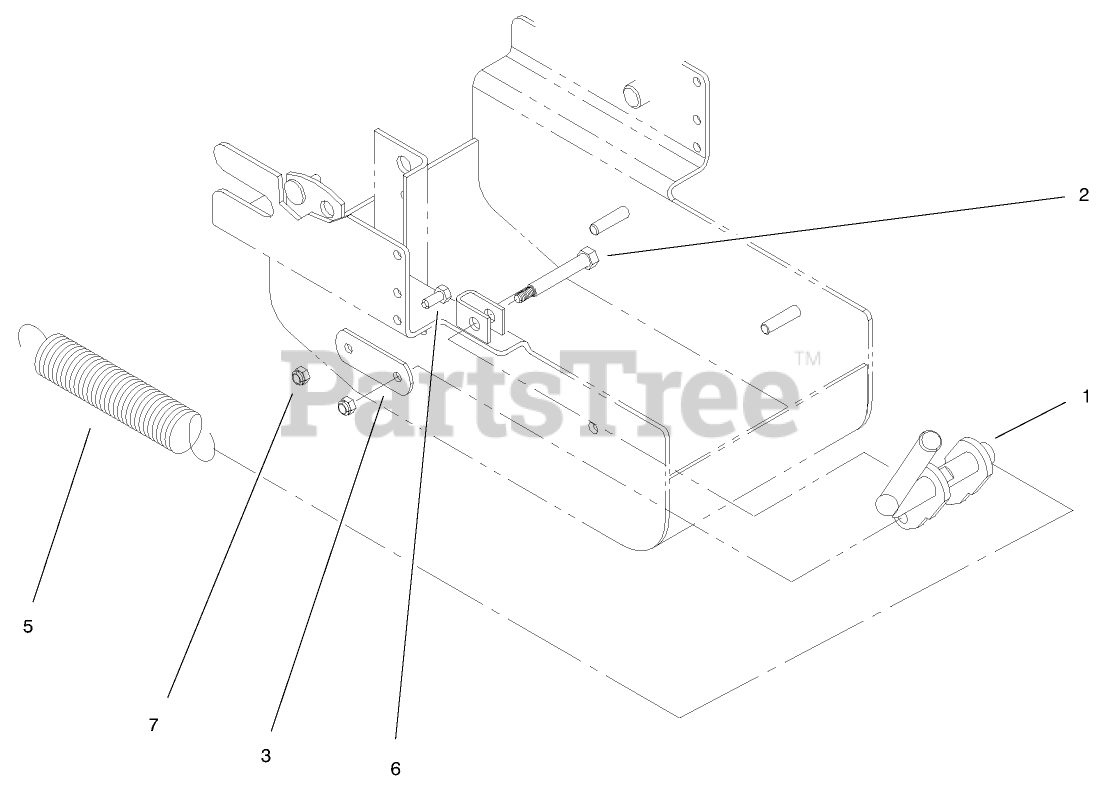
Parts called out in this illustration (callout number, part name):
2	SHOULDER BOLT
3	BRACKET-PIVOT
5	SPRING-EXT
6	SCREW-HH
7	NUT-LOCK, NI
